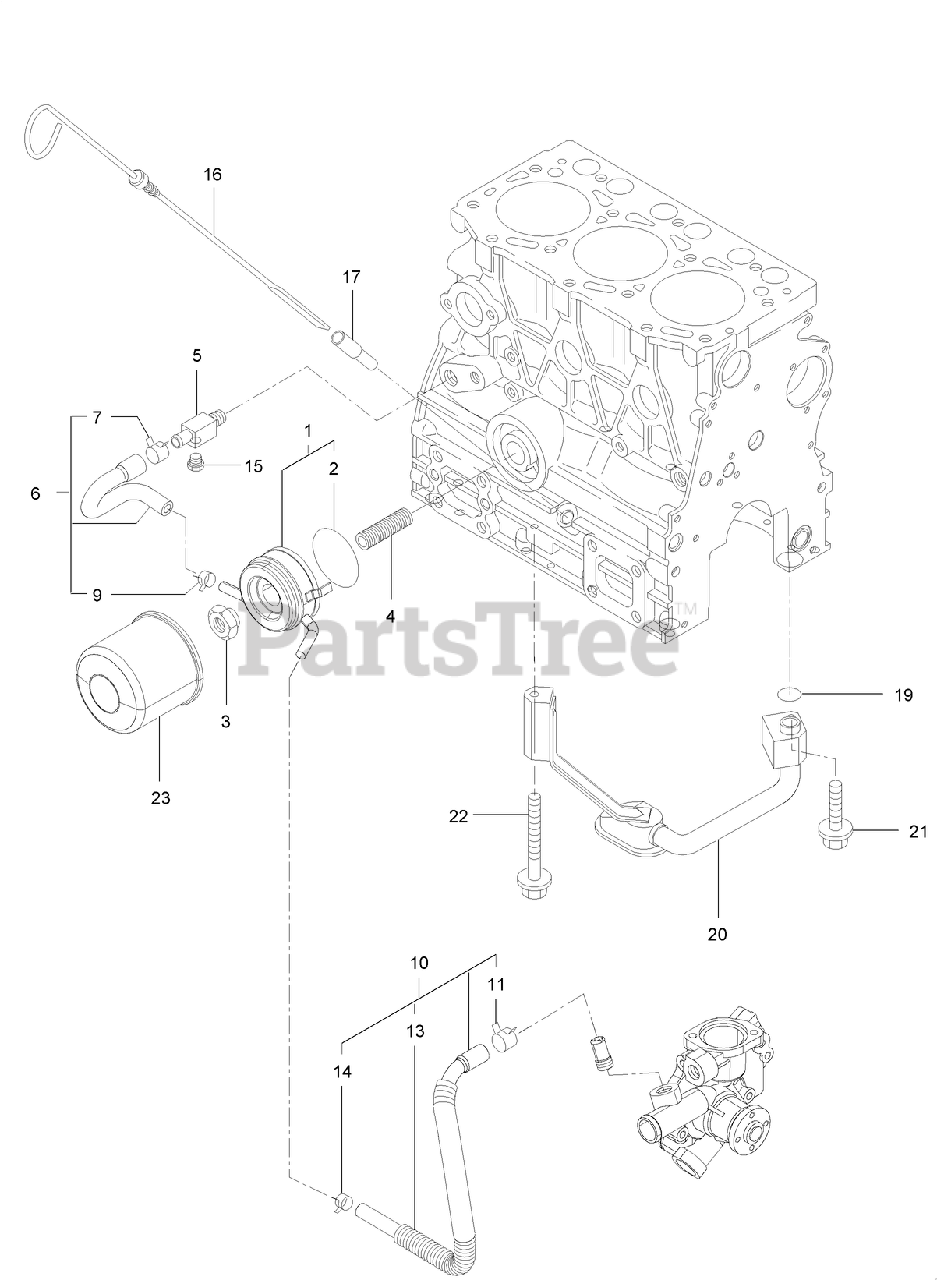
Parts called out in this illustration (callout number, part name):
1	COOLER-OIL
2	O-RING
3	NUT-COOLER, OIL
4	STUD-LO FILTER
6	PIPE ASM-COOLER IN
9	CLAMP-HOSE
10	PIPE ASM
14	CLAMP-HOSE
15	PLUG-DRAIN
16	DIPSTICK
17	GUIDE-DIPSTICK
19	O-RING
20	PIPE ASM-OIL INLET
23	FILTER ENGINE OIL
